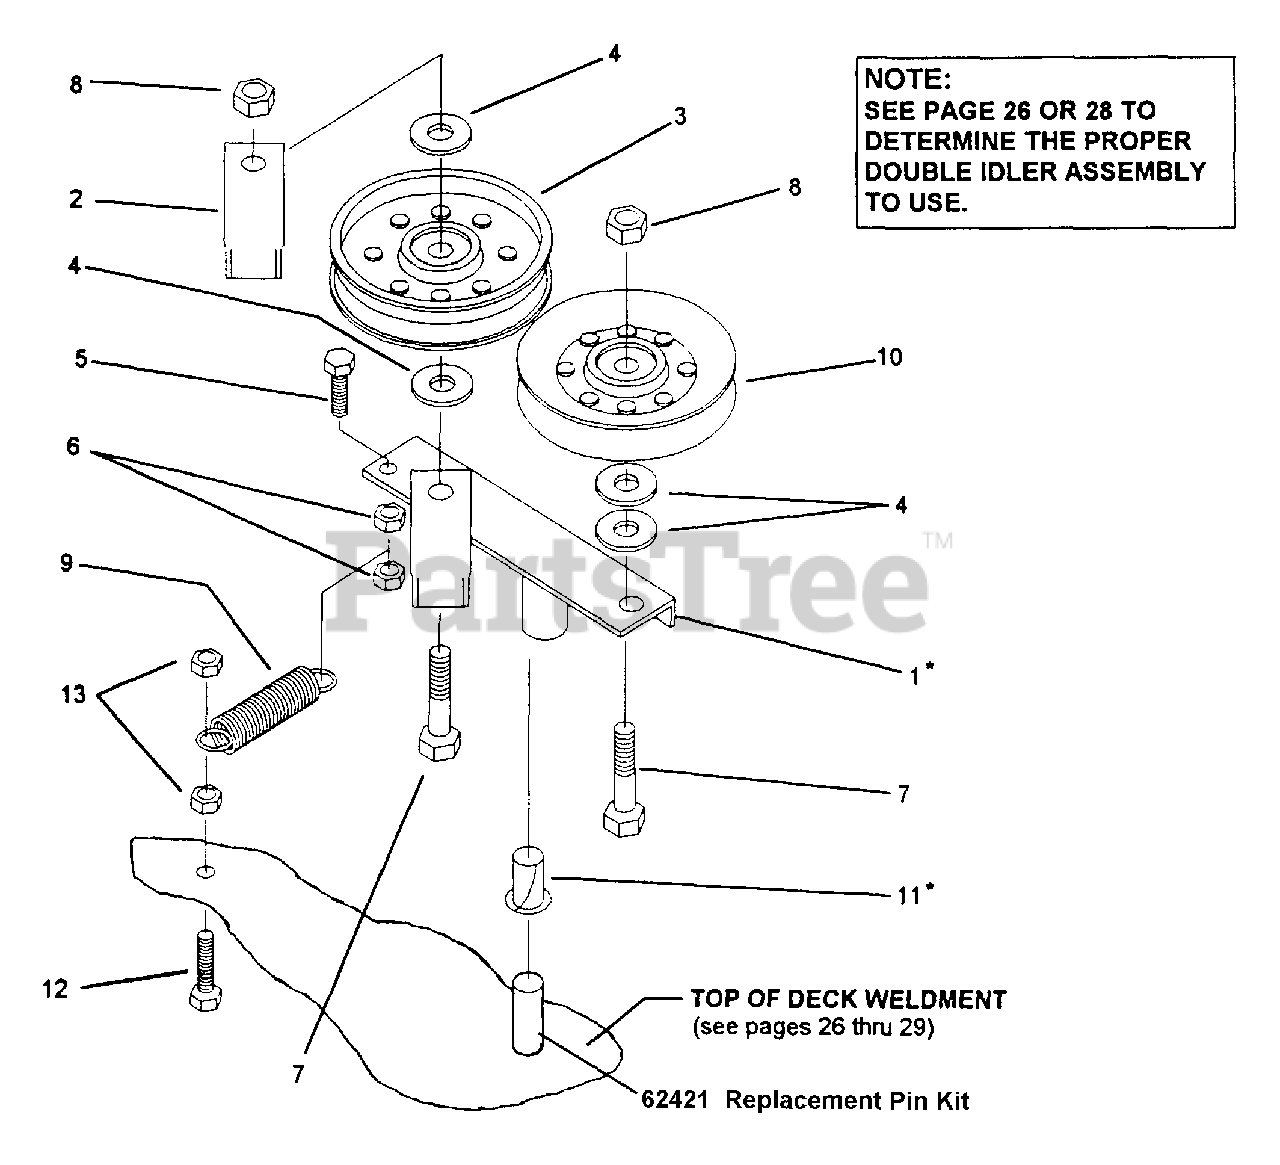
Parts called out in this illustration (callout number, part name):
1	DOUBLE IDLER WELD.
2	PLATE, BELT STOP
3	PULLEY, FLAT IDLER 1/2" BORE, 4" O.D.
4	WASHER, FLAT 1/2" STD.
5	BOLT, 3/8-24 x 1-1/4" GR. 5
6	NUT, 3/8-24, M-F LOCK
7	BOLT, 1/2-13 x 2", GR. 5
8	NUT, 1/2-13, STOVER
9	SPRING, EXTENSION, 3/4" x 4" O.A.L.
10	PULLEY, V-IDLER, 1/2" BORE, 4-3/8" O.D.
11	BUSHING, NYLON, 5/8" BORE
12	BOLT, 3/8-24 x 1-1/4", GR. 5
13	NUT, 3/8-24, M-F LOCK
